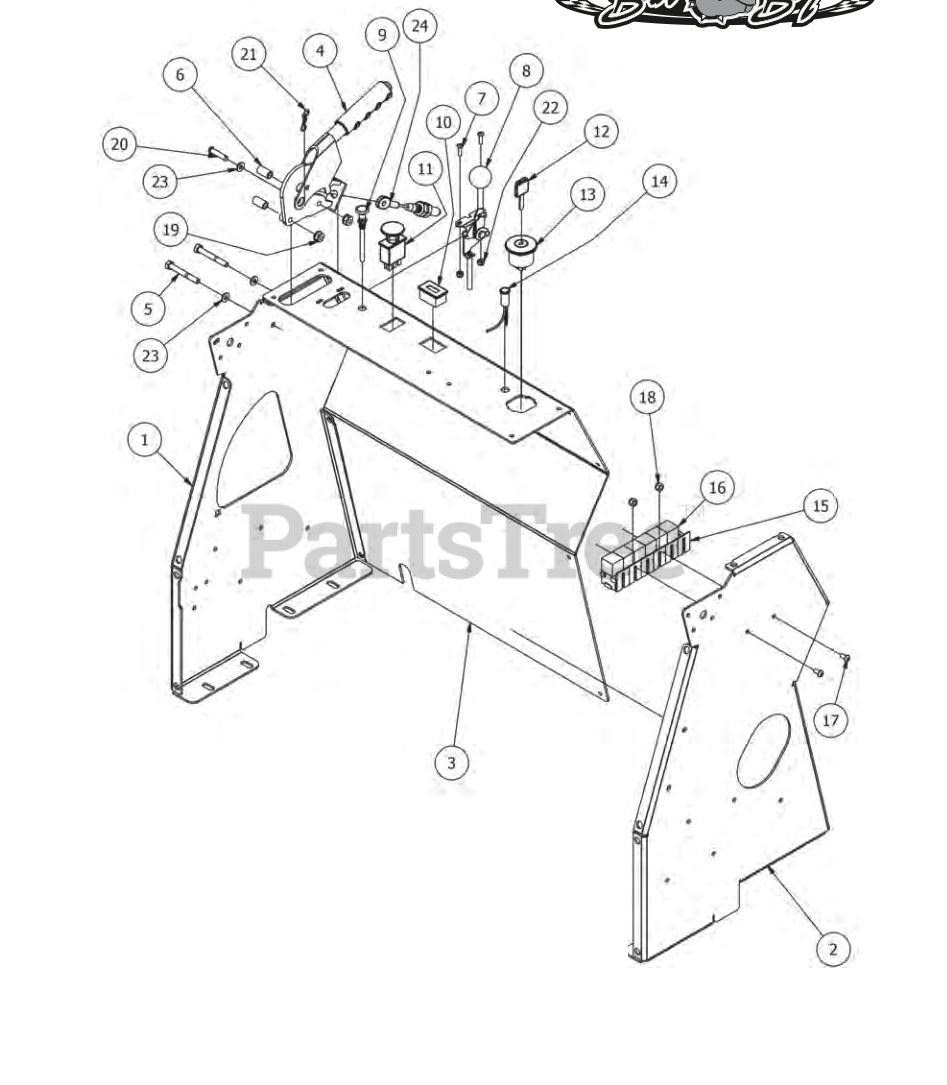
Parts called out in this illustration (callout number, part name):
1	2015 Podium Panel Left
2	2015 Podium Panel Right
3	2015 Podium Front Panel
4	Brake Handle-Stand On
5	5/16" x 2 1/2" Bolt
6	Brake/Latch Spacer-Stand On
7	10-24 x 1 BS C/S 18-8 SS
8	Throttle-All Outlaws
10	Tachometer
11	PTO Engager
12	Ignition Key
13	Ignition Switch
15	Wiring Harness - 2015 Stand On
16	Relay Terminal
17	1/4" x 1/2" BS C/S 18-8 SS
18	1/4" Nylock Nut
19	5/16-18 Nylon Flange Nut
20	PIN .312 PIN
22	#10 Nylock Nut
23	1/4" Flat Washer
24	Brake Cable
